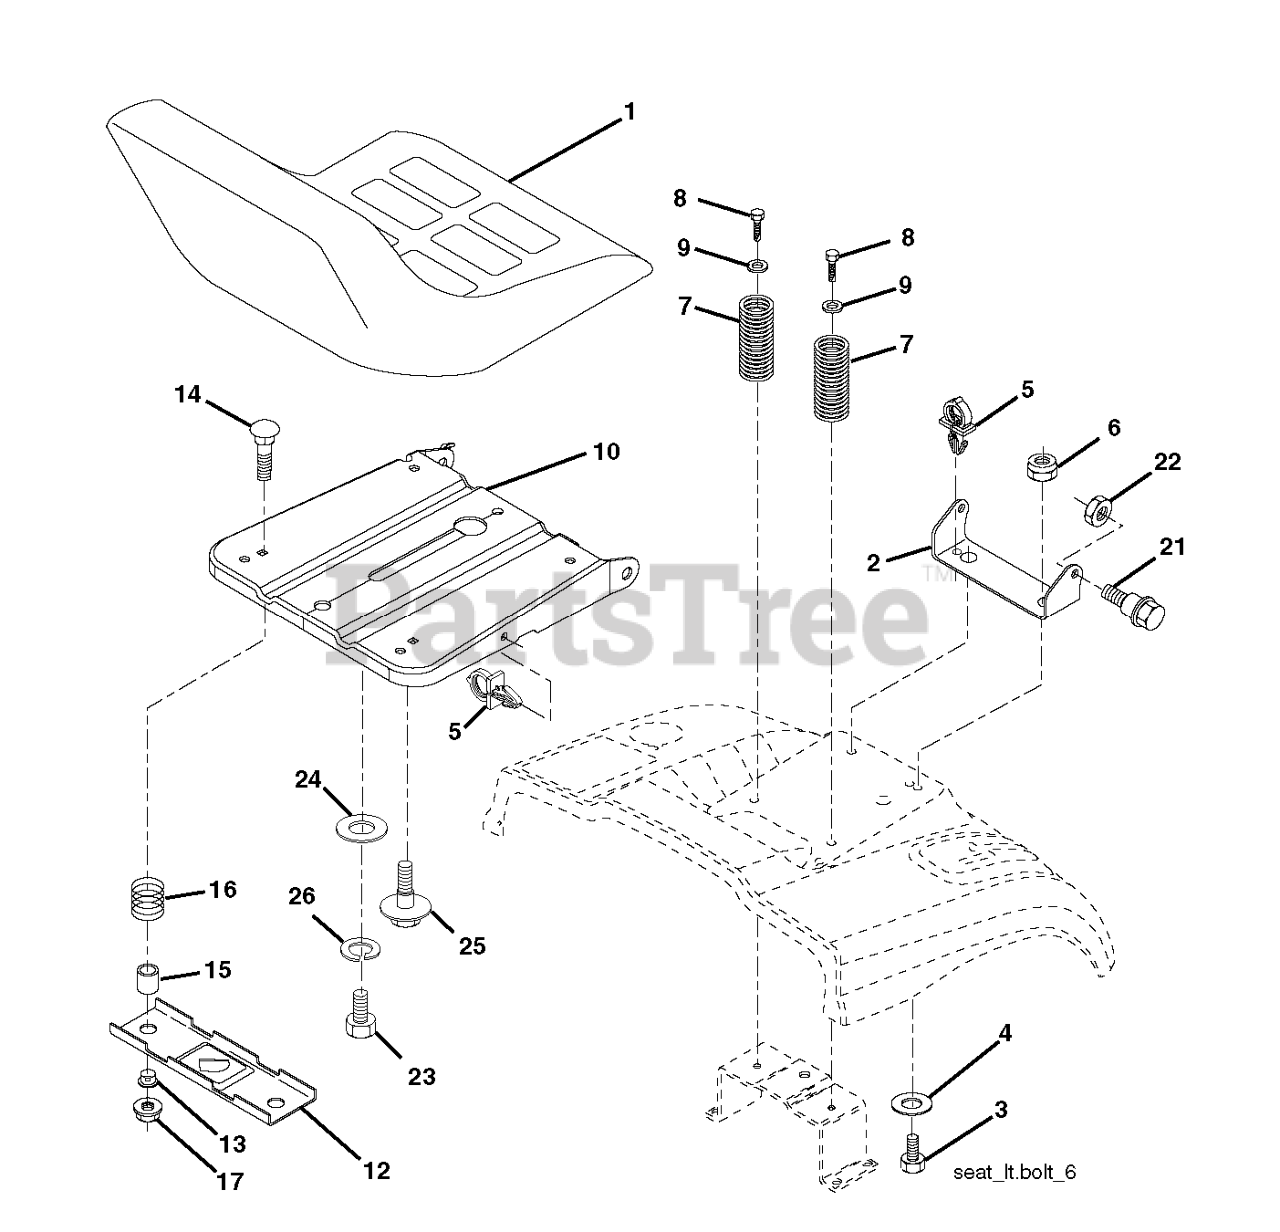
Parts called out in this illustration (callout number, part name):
1	SEAT.XG090.BLK.KB/BLT.NO-LOG
2	SEAT PIVOT BRKT
3	BOLT, HEX 3/8-16X1
6	NUT
7	SPRING COMPRESSION
8	SCREW 3/8-16X1
9	WASHER
10	PAN.ASM.SEAT.1SLOT
12	BRKT.MNTNG.SWITCH.SEAT.BLACK
14	BOLT.ROUND.HEAD.SQUARE.NECK
15	SPACER SPLIT 28X.96
17	NUT T
21	BOLT.SHOULDER.5/16-18
22	NUT.71038.31-18.HEX.NYLOCK
23	BOLT.HEX.BLACK
25	BOLT,SHOULD
26	LOCKWASHER
